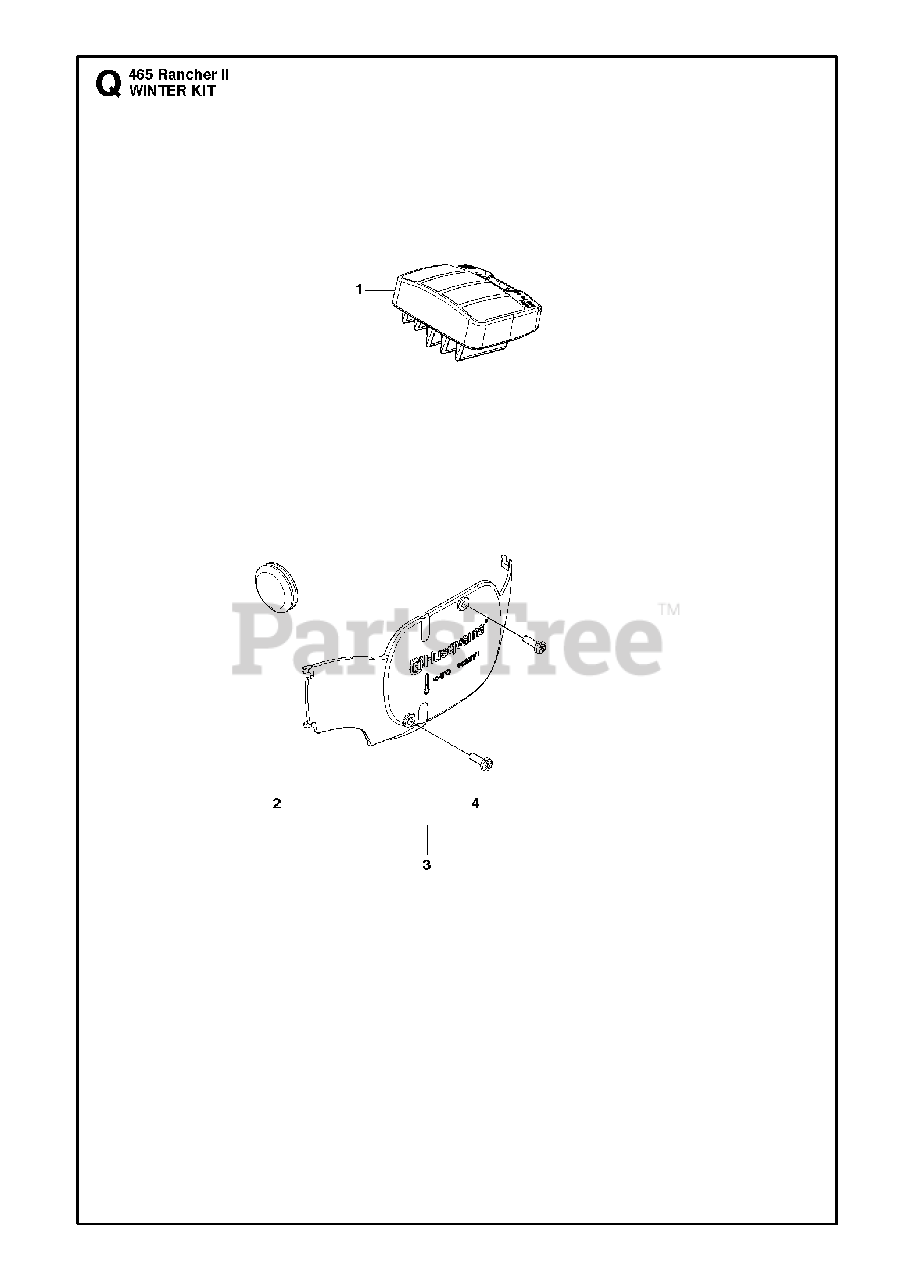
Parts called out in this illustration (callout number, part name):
1	AIR FILTER ASSY
2	PLUG
3	WINTER KIT
4	SCREW
